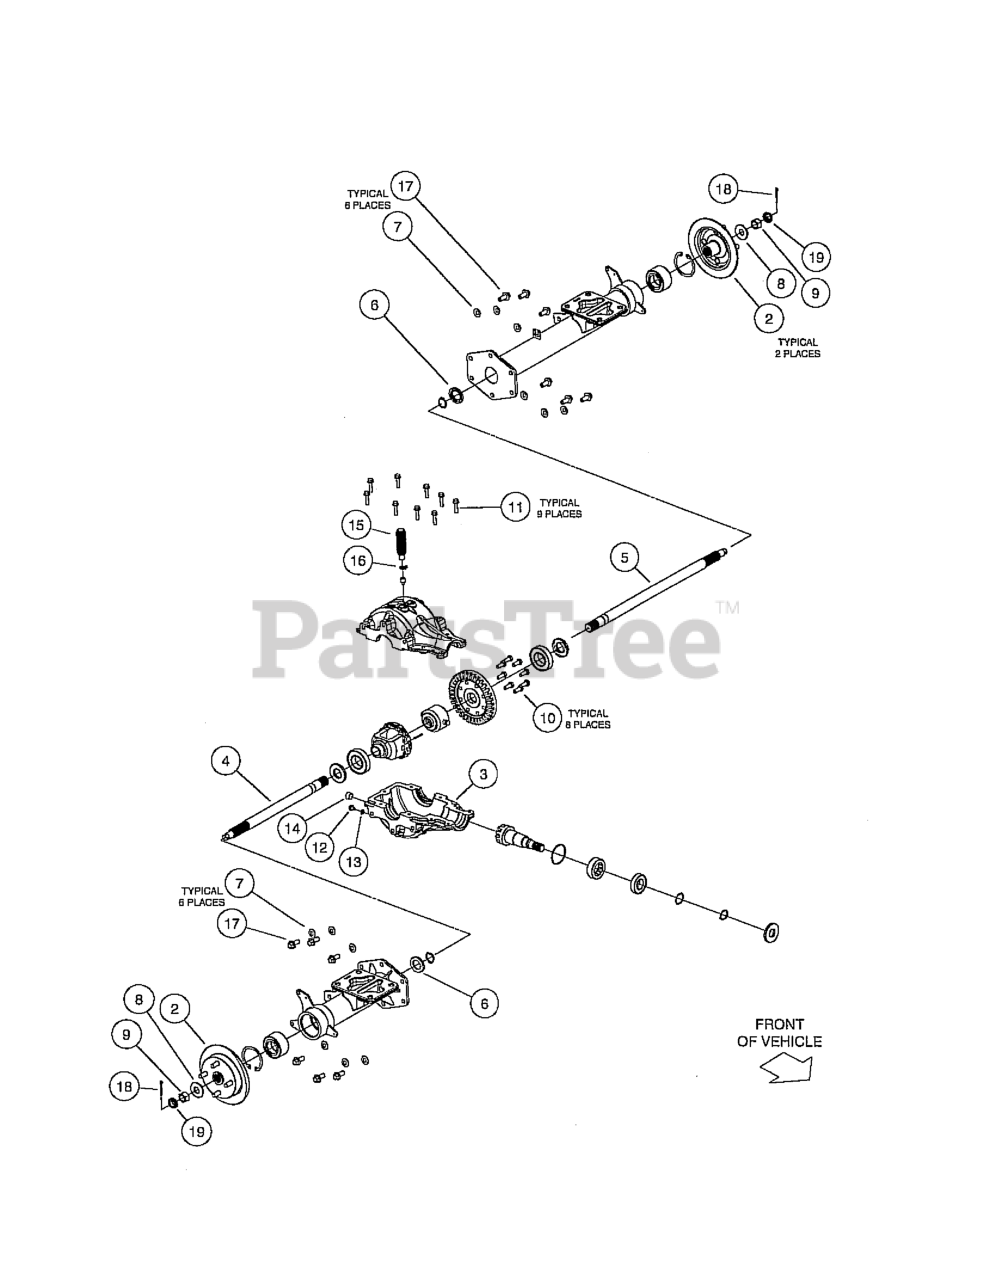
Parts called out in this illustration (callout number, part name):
3	GEARCASE, LOWER, MACHINED
6	WASHER, COUNTERBORED 51 X 30
7	WASHER, BELLEVLE, 1.063 X .043
8	WASHER, BELLEVILLE, 49 X 4
9	NUT, HEX, M20 X 1.5, MODIFIED
10	SCREW, M10 X 25
11	SCREW, HEX FLANGE, M8 X 35
12	PLUG,3/8-16, HEX FLANGE
13	WASHER, .625 X .382 X .60
14	PLUG, SQUARE SKIT, 1/12-14,PTF
15	BELLOWS, VENT, UPPER HOUSING
16	CLAMP, HOSE, DW-9.5
17	SCREW, HEX FL, M12 X 1.75 X 30
18	PIN, COTTER, 5/32 X 1.25
